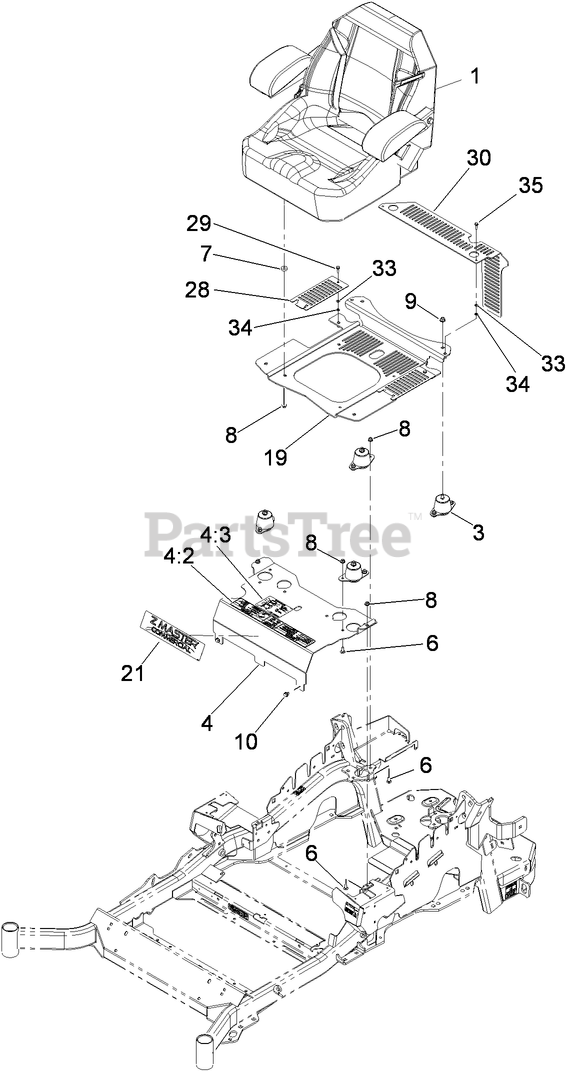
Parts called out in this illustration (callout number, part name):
1	SEAT-STANDARD
3	ISOLATOR-SEAT
4	MOUNT-SEAT
4:2	DECAL-CONSOLE
4:3	DECAL-SERVICE AID
6	SCREW-CARR
7	SPACER-PIN, MOUNTING
8	NUT-HF, NI
9	NUT-HF, NI
10	SCREW
19	SEAT BASE ASM
29	SCREW-HWH
33	WASHER-FLAT
34	NUT-RETAINER
35	SCREW-HHF
